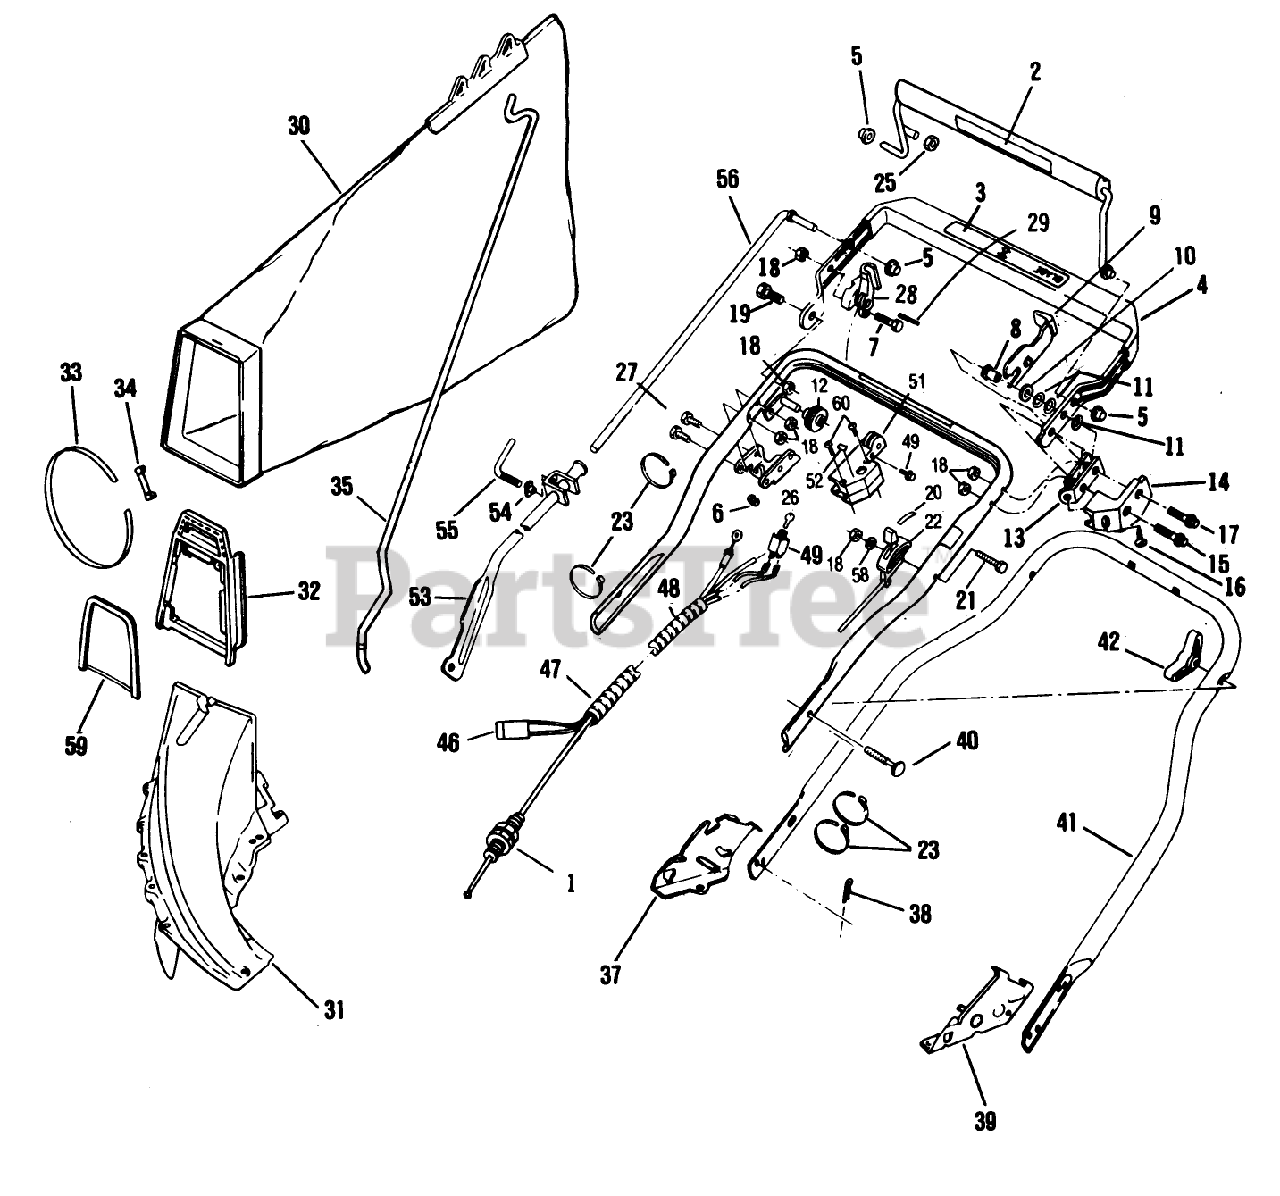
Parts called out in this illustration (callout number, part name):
1	CONTROL CABLE
6	RET. RING
8	SPACER
10	WASHER M
12	PULLEY PL
13	DOWN STOP
14	LOCKOUT GUARD
15	BOLT SHOU
16	SCREW F
17	SCREW
18	LOCKNUT E
19	BOLT
25	NUT ACORN
28	CAM HOFFER
30	ORD 89816 WHOLE GOODS
32	CHUTE - ADAPTER
35	ROD GRASSBAG
37	BRACKET ASM - HANDLE, SP, RH
38	HAIR PIN
39	BRACKET ASM - HANDLE, SP, LH
40	BOLT QUALITY
42	NUT-WING
53	CONTROL LEVER AY
56	CONTROL ROD
58	WASHER-FLAT
59	CHUTE BRACE
60	SCREW LAWRENCE
